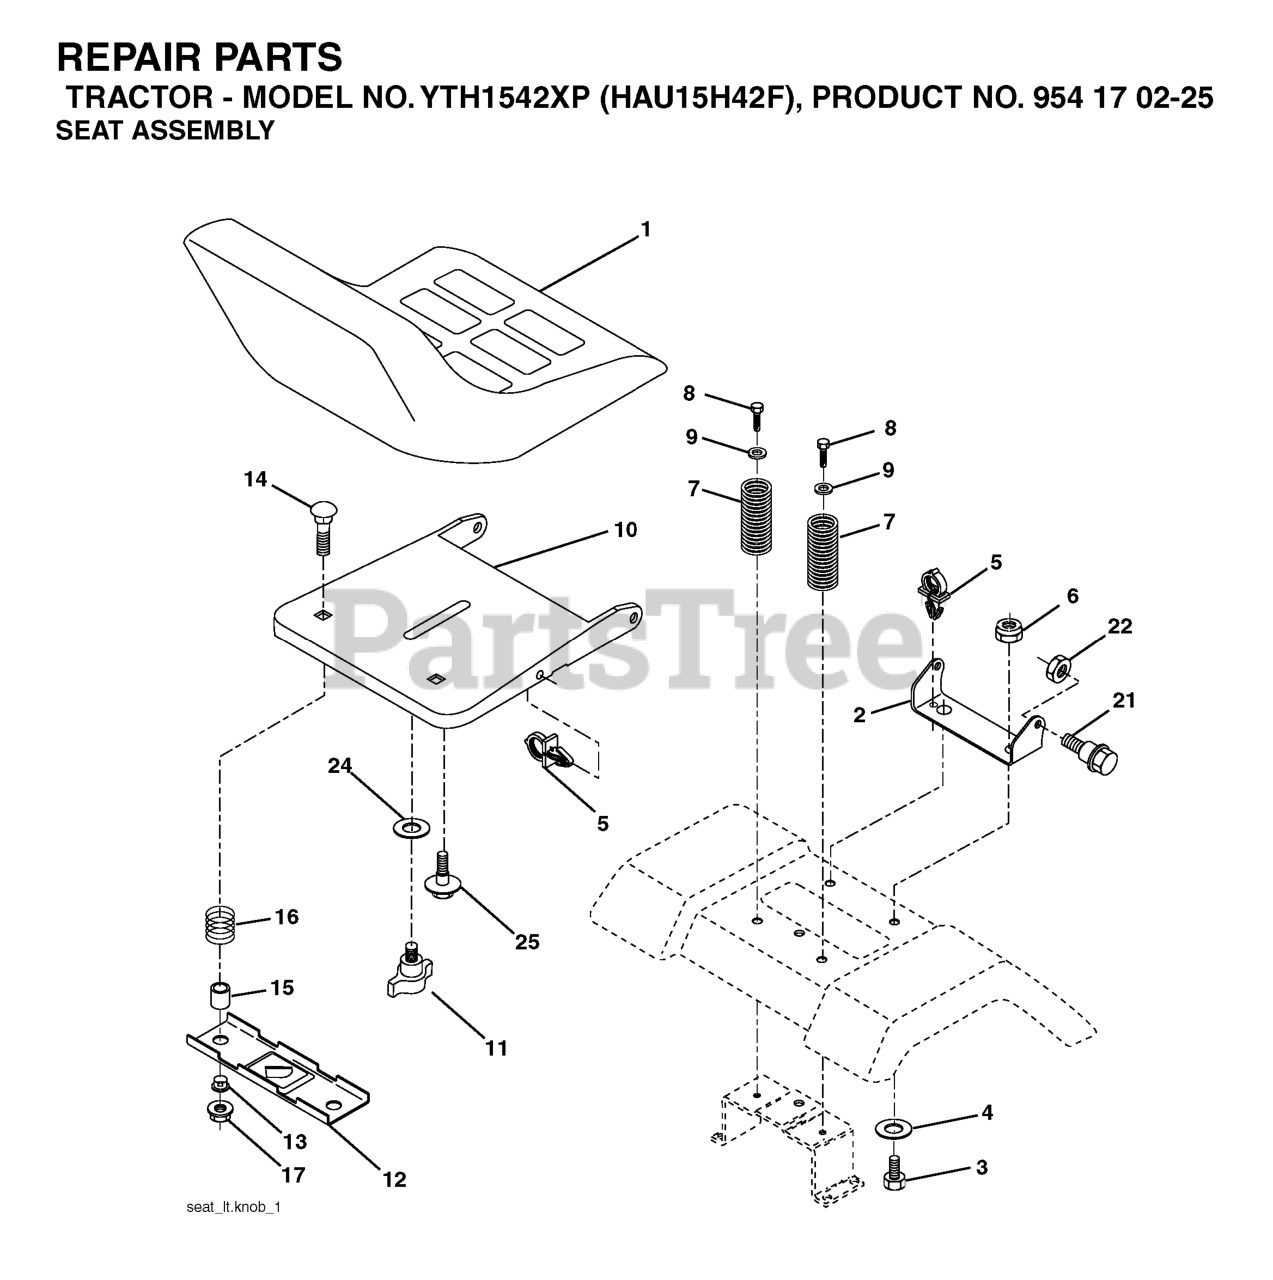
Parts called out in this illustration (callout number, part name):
1	SEAT
2	SEAT PIVOT BRKT
3	BOLT, HEX 3/8-16X1
6	NUT
7	SPRING COMPRESSION
8	SCREW 3/8-16X1
9	WASHER
10	PAN SEAT
11	KNOB.SEAT.ADJ.WINGNUT
12	BRKT SWITCH
14	BOLT.ROUND.HEAD.SQUARE.NECK
15	SPACER SPLIT
16	SPRING COMPRESSED
17	NUT T
21	BOLT.SHOULDER.5/16-18
22	NUT.71038.31-18.HEX.NYLOCK
25	BOLT,SHOULD
